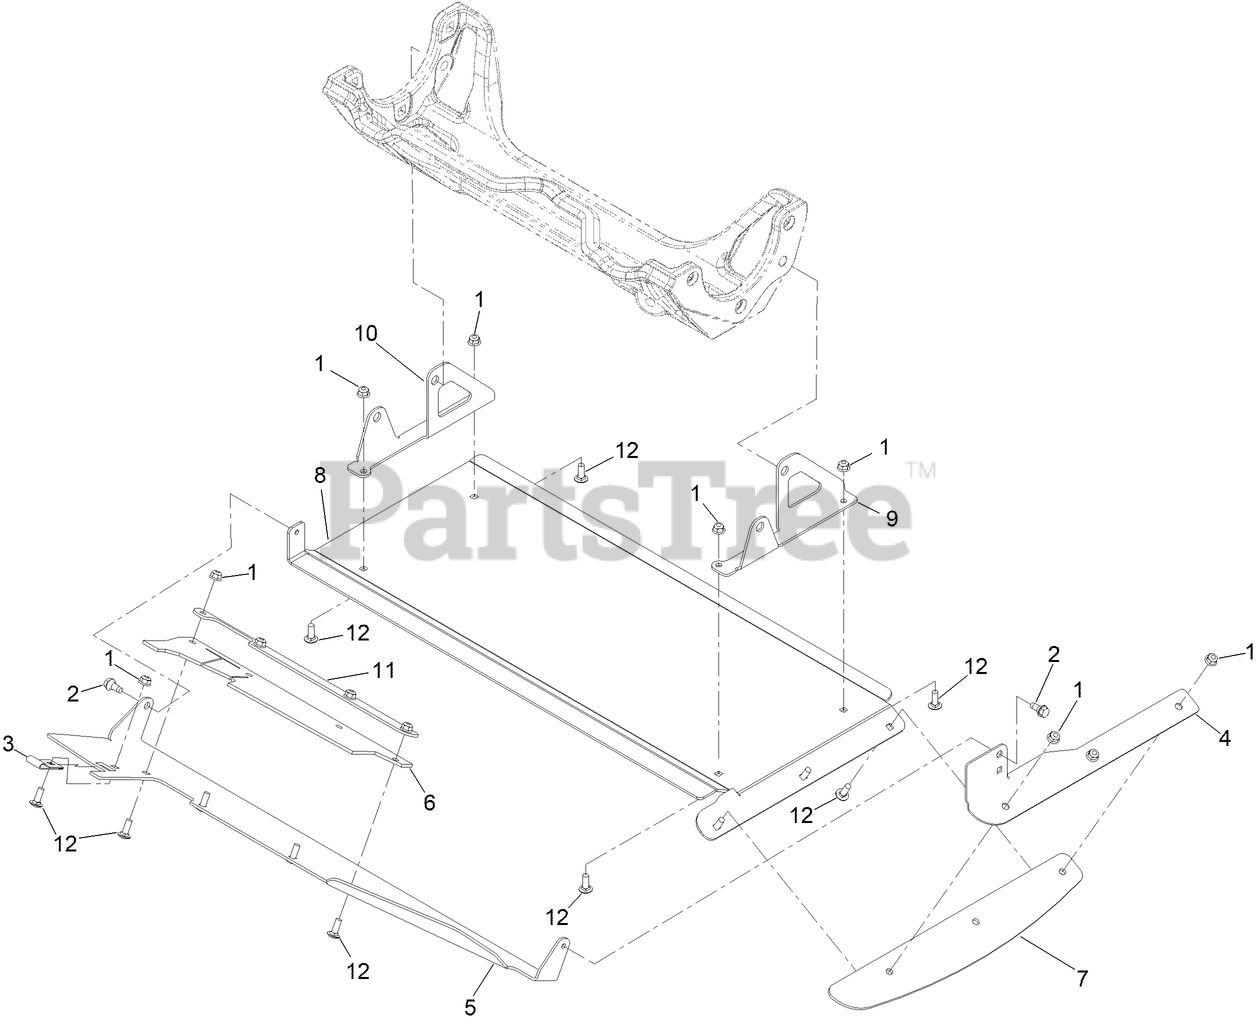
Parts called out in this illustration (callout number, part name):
1	NUT-HF, NI
2	SCREW-SHOULDER
3	BEARING-STRAP, NYLON
4	BRACKET-FLAP, LH
5	PANEL-DISCHARGE
6	FLAP-DISCHARGE
7	FLAP-RUBBER
8	PANEL-DISCHARGE
9	BRACKET-TUNNEL HANGER LH
10	BRACKET-TUNNEL HANGER RH
11	SUPPORT-LH FLAP RD96
12	BOLT-CARR
